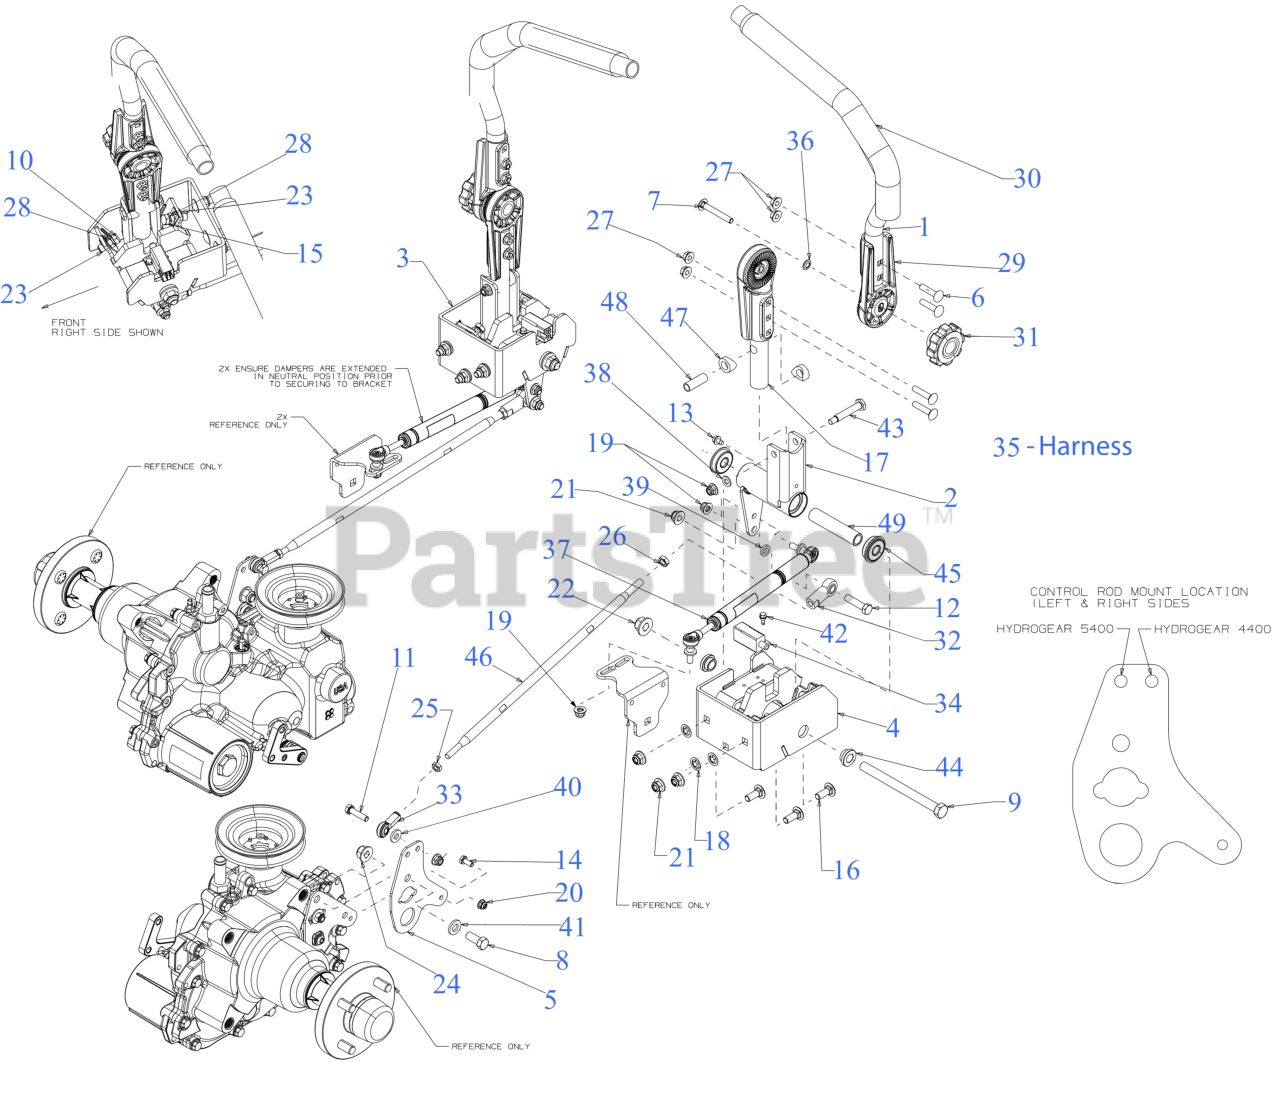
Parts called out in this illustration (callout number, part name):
2	PIVOT CONNECTOR
3	PIVOT LAPBAR HOUSING (LH)
4	PIVOT LAPBAR HOUSING (RH)
5	LAPBAR NEUTRAL PLATE
6	CARRIAGE BOLT 5/16-18 x 1.50
7	BOLT 5/16-18 x 2.50 GR1
8	SCREW 7/16-14 x 1.00 GR5
9	SCREW 1/2-13 x 6.0 GR5
10	SCREW 3/8-16 x 1 GR5
11	SCREW 5/16-18 x 1.25 GR5
12	SCREW 3/8-16 x 1.50 GR8
13	SCREW 1/4-20 x .375
14	SCREW 1/4-20 x .620 GR5
15	SCREW 3/8-16 x 1.25 GR5
16	CARRIAGE BOLT 3/8-16 x 1.00 GR5
19	FLANGE LOCK NUT 5/16-18
20	FLANGE LOCK NUT
23	U NUT 3/8-16
24	HEX FLANGE LOCK NUT 7/16-14
25	HEX JAM NUT 5/16-24 GR5
26	HEX JAM NUT 3/8X24
27	HEX FLANGE NUT
28	HEX JAM NUT 3/8-16 GR5
29	ADJUSTMENT HANDLE
31	KNOB-5/16-18
32	BALL JOINT
33	END ROD- 5/16 (LH)
34	INTERLOCK SWITCH (NO/NC)
35	ADAPTER HARNESS - LAPBAR
37	DAMPENING CYLINDER
38	FLAT WASHER
39	FLAT WASHER
40	FLAT WASHER.344X.75X.1
41	FLAT WASHER
42	SHOULDER SCREW
43	SHOULDER SCREW
44	SHOULDER SPACER .520X.250X.730
45	ROLLER BEARING .5X1.37X.44
46	PUMP CONTROL ROD
47	NYLON SPACER
49	SPACER.53X.75X3.52
